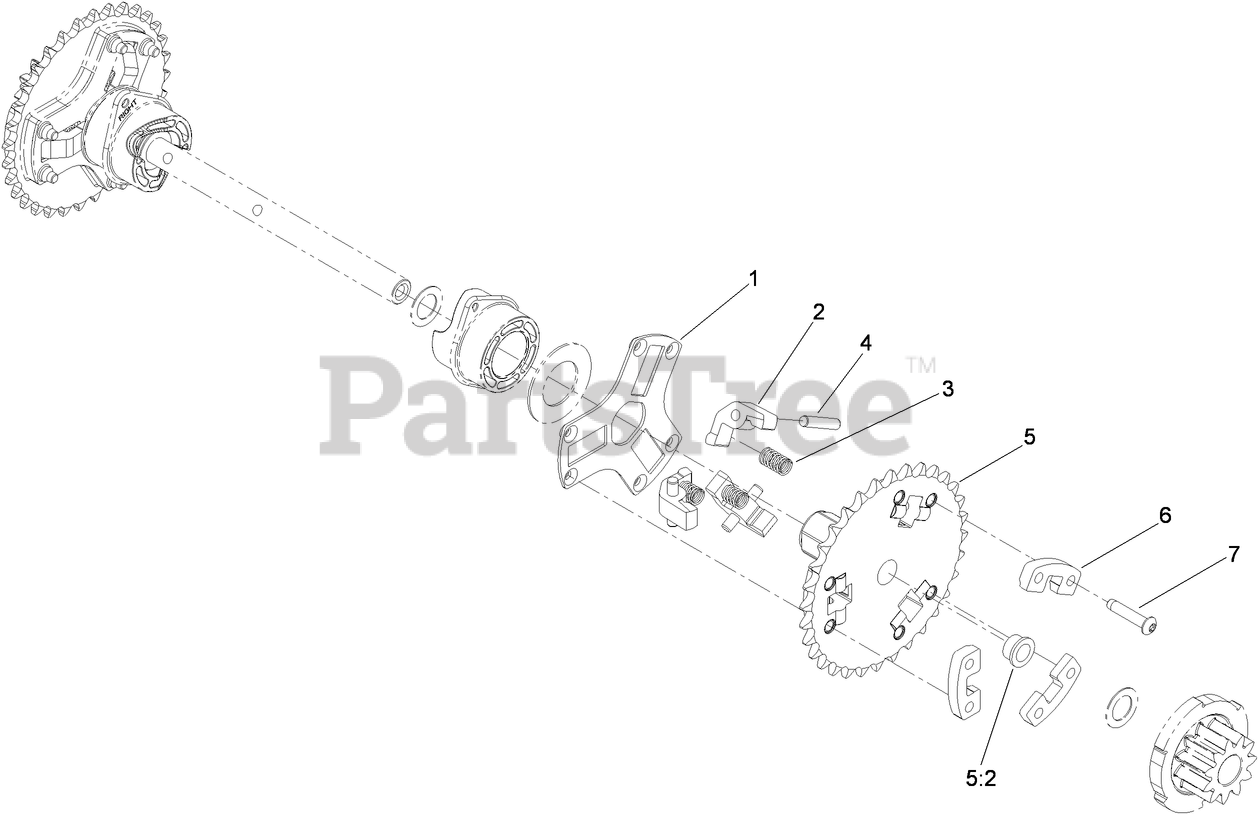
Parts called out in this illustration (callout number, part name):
1	RETAINER-PIN, PAWL
2	PAWL-CLUTCH
3	SPRING-COMPRESSION
4	PIN-DOWEL
5	32T SPROCKET ASM
5:2	BUSHING-FLANGE
6	SUPPORT-PAWL
7	SCREW-TTH, THREAD ROLLING
